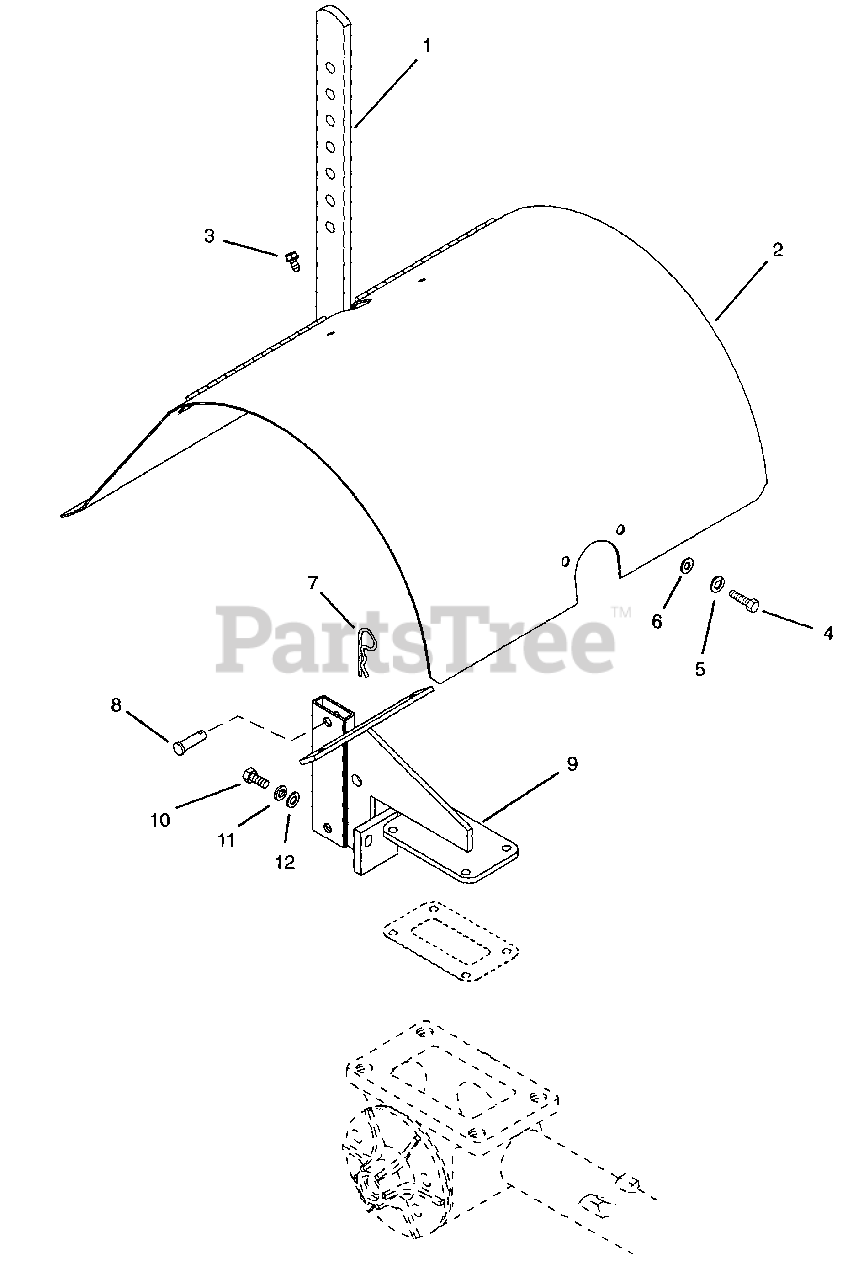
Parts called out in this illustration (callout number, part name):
1	DEPTH STICK
2	TINE HOOD W/ DECALS
3	@SCR-TAP .25-20X.50 HWH TR YWZ
4	@BLT-HEX .31-18X.50 GR5 YWZC
5	WSHR-LOCK INT .31 YWZC
6	@WSHR-FL-STL.312X.734X.065 YWZ
7	PIN-HAIR-EXT .12X.31X2.37 YWZC
8	PIN-CLEV .38 X 1.06
9	DEPTH STICK HOLDER
10	@BLT-HEX .31-18X1.00 GR5 YWZC
11	@WSHR-LK .31X.078 REG YWZC
12	@WSHR-FL-STL.344X.688X.065YWZC
